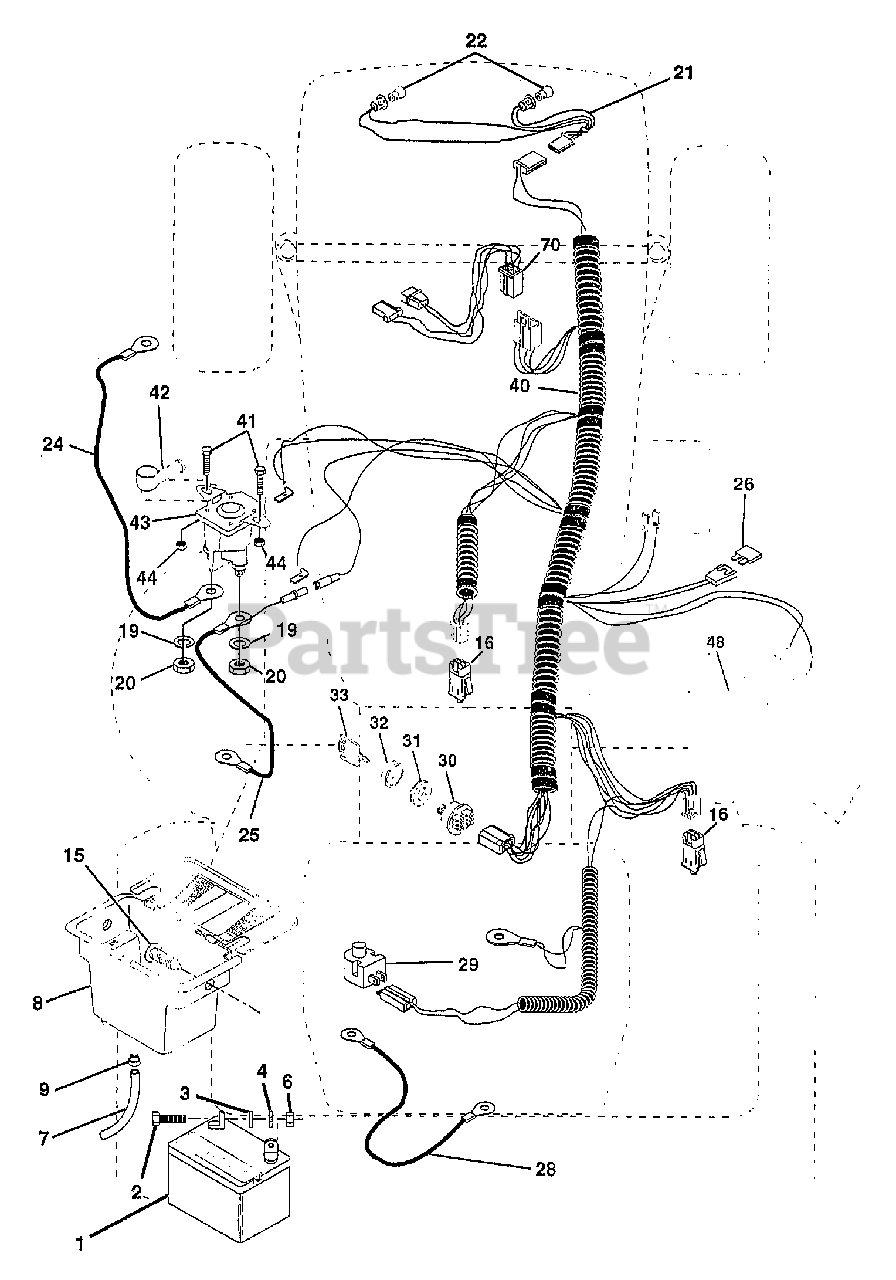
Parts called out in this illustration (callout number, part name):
2	BOLT LT
3	WASHER
4	LOCKWASHER
7	TUBE T
8	"CASE,BATTERY.MECH"
9	HOSE CLAMP T
15	FASTNER.SNAP-IN
16	SWITCH INTERLOCK
20	NUT
21	"HARNESS,LIGHT SOC"
22	HEADLAMP BULB
24	CABLE.BTRY.6GA.RD
25	CABLE.BTRY.6GA.38
26	FUSE HYT
28	CABLE T
29	SWITCH SEAT
30	SWITCH IGN 4POS
31	NUT IGNITION
32	COVER KEY SWITCH
33	KEY
40	HARNESS IGNITION
41	BOLT HXHD FIN
44	NUT HXKEP 1/4X20
48	ADAPTER AMMETER
70	HARNESS.ENG.DUAL
